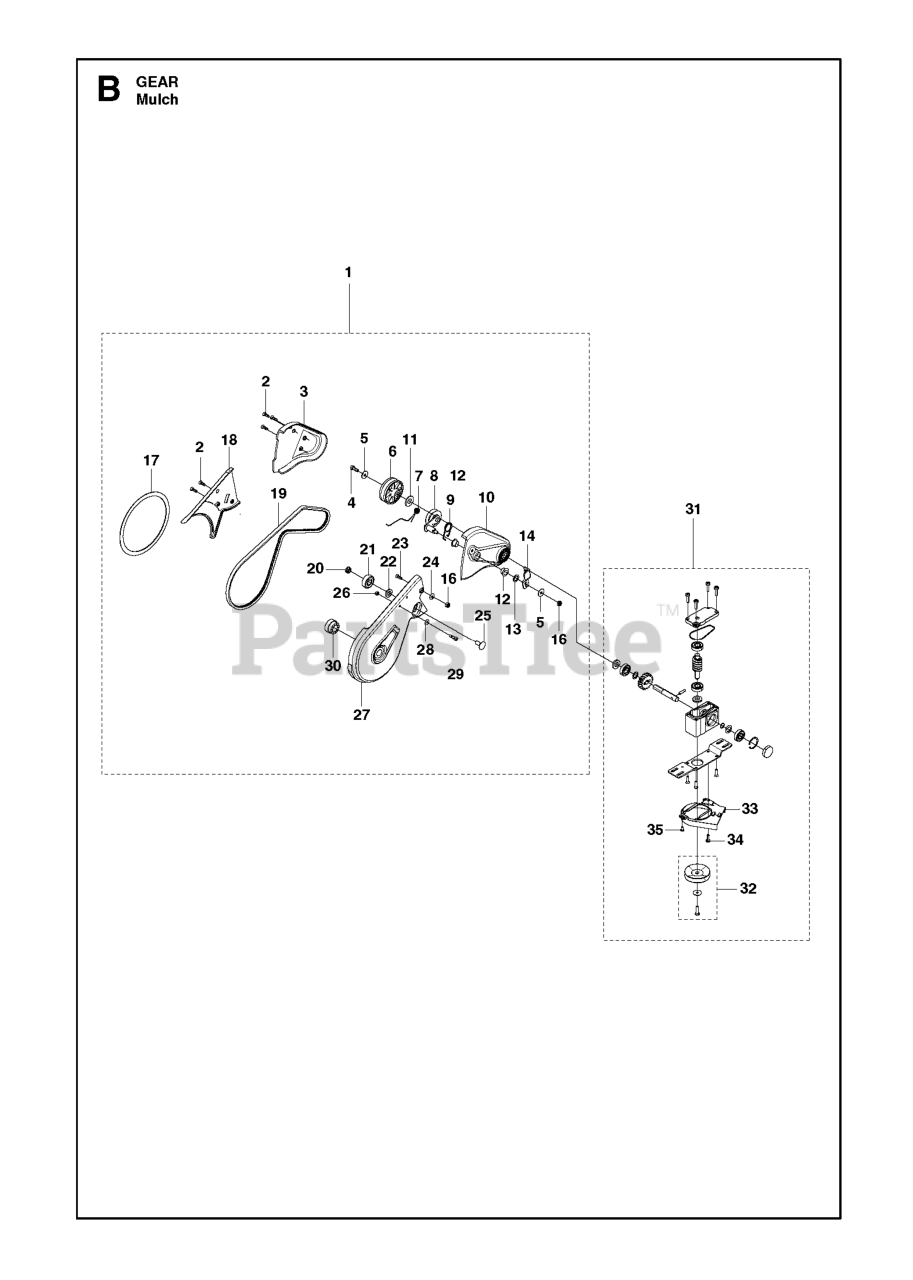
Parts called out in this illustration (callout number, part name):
5	WASHER 19X6X1
16	NUT FLANGE - M6
21	BALL BEARING 6201-2RS1
